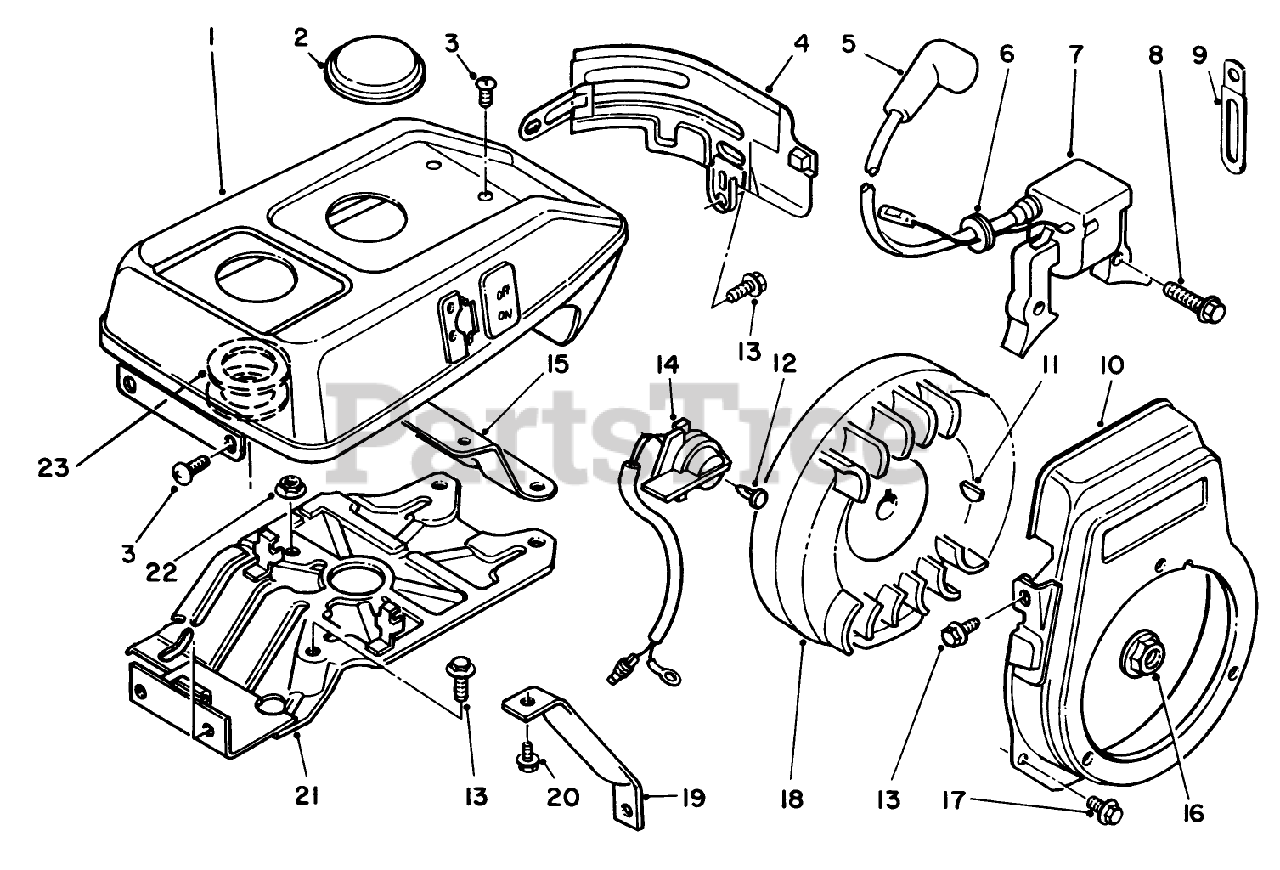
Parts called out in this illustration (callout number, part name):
5	CAP-SPARKPLUG
9	CLAMP
20	SCREW-HHF
